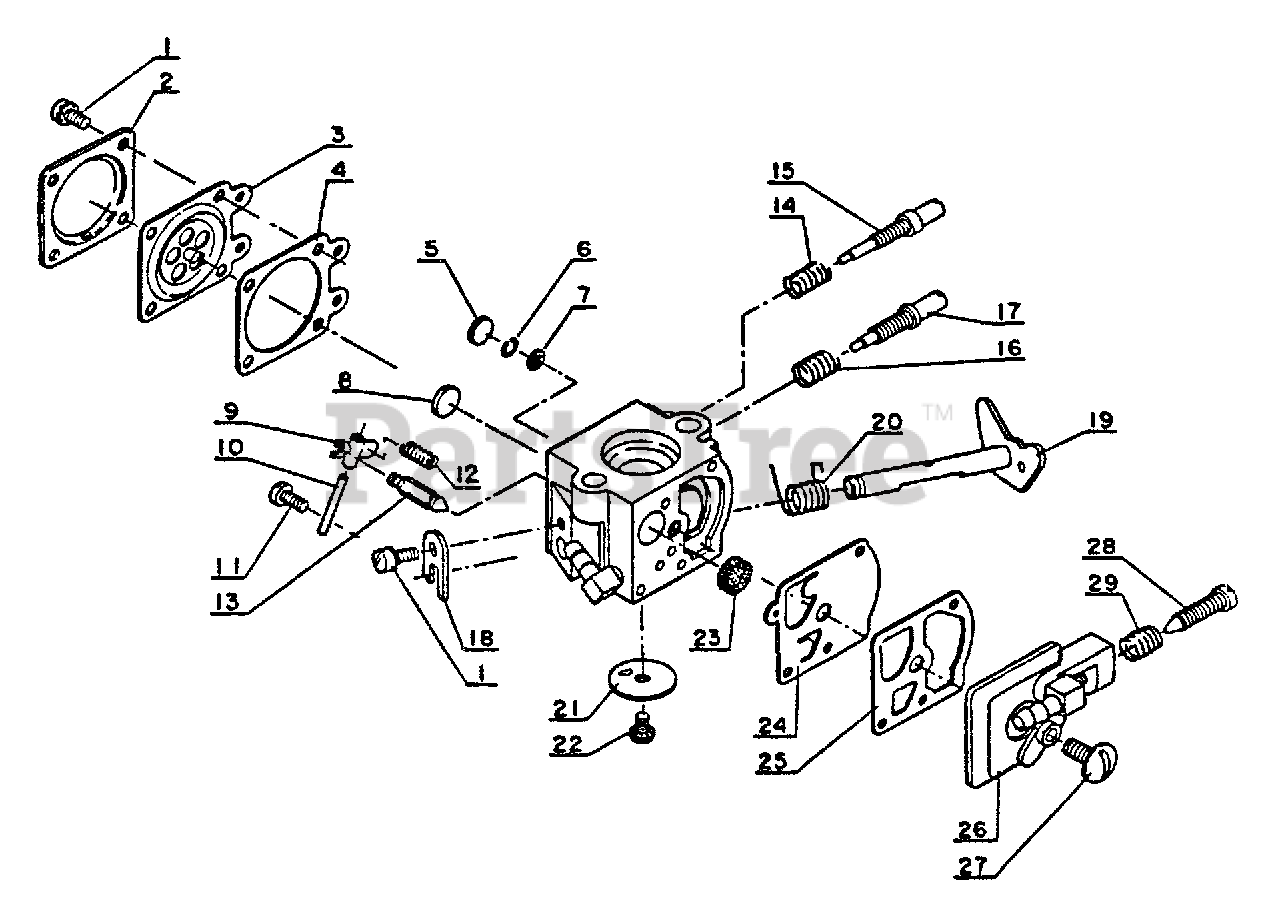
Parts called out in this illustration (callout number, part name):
2	COVER, METERING DIAPHRAGM
3	DIAPHRAGM, METERING
4	GASKET, METERING DIAPHRAGM
5	PLUG, WELCH
6	RING, RETAINING
7	SCREEN, SPARK ARRESTER
8	PLUG, WELCH
9	LEVER, METERING
10	PIN, METERING LEVER
11	SCREW, METERING LEVER PIN
13	VALVE, INLET NEEDLE
14	SPRING, NEEDLE
15	NEEDLE, HIGH SPEED
16	SPRING, NEEDLE
17	NEEDLE, IDLE
18	CLIP, THROTTLE SHAFT
19	SHAFT, THROTTLE
20	SPRING, THROTTLE RETURN
21	VALVE, THROTTLE
23	SCREEN, FUEL INLET
24	DIAPHRAGM, PUMP
25	GASKET, FUEL PUMP
26	COVER, PUMP
28	SCREW, IDLE ADJUST
29	SPRING, IDLE ADJUST
